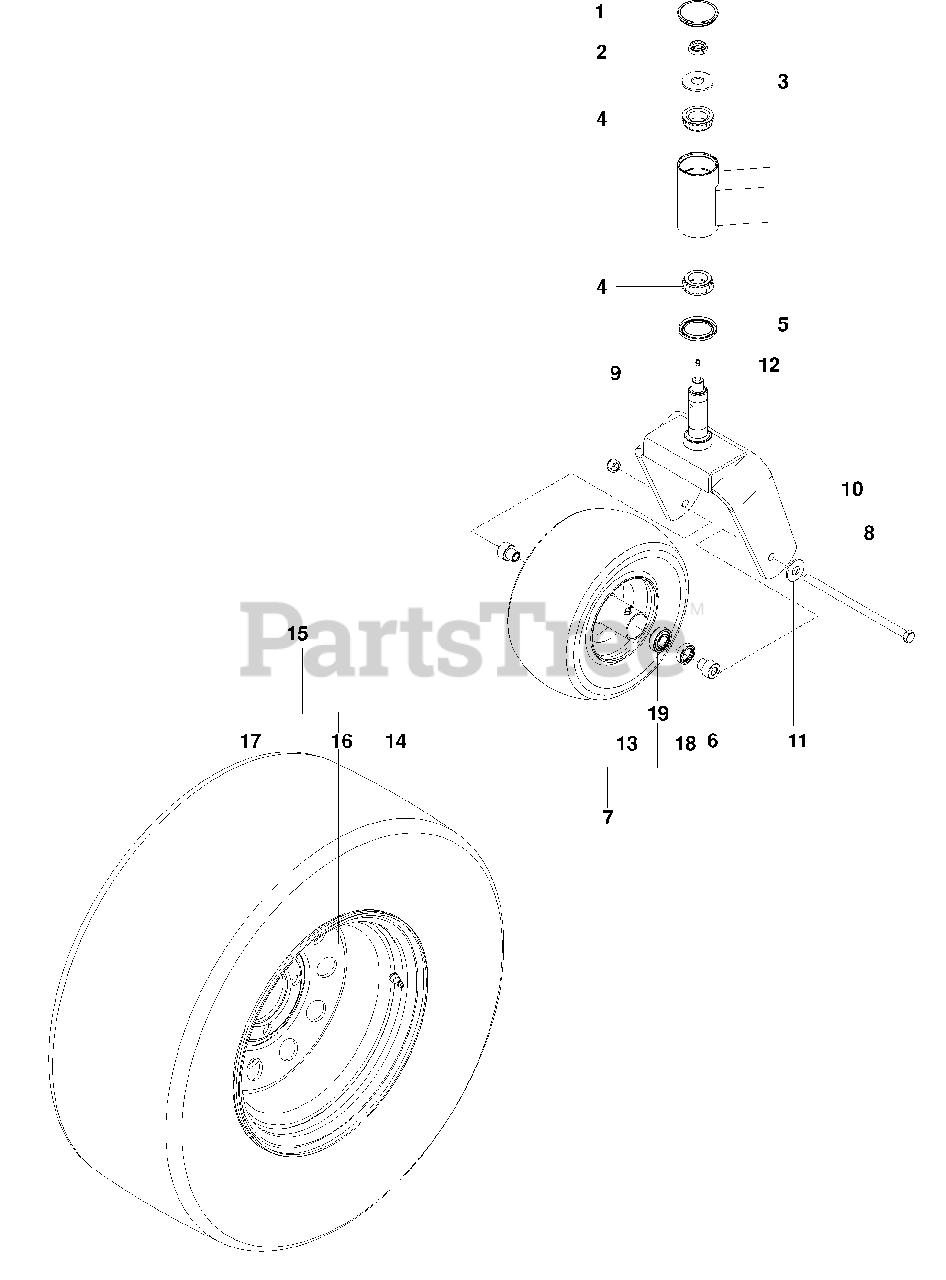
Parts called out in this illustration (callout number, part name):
2	Bolt 7/16-20 X 1 1/2 Hex Nyl
3	Washer 3/4 Hardened
4	Bearing, Tapered
5	Seal, Bearing
6	Axle Spacer
7	Tire Assy 13 X 6.5, Flt Free
8	Bolt 1/2-13 X 9 1/2 Hex Nyloc
9	Nut 1/2-13 Hex Flg Nyloc
10	Fork, Caster
11	Washer 1/2 Sae
12	Zerk
13	Zerk
14	Stem, Valve
15	Tire Assy 23 X 10.5 966060901, 966883801
16	Rim 12 X 1.125 Neg Offset 966060901, 966553801
17	Tire 23 X 10.5 Turf Master 966060901, 966553801
18	Seal, Caster Tire
19	Bearing (Cup And Cone)
